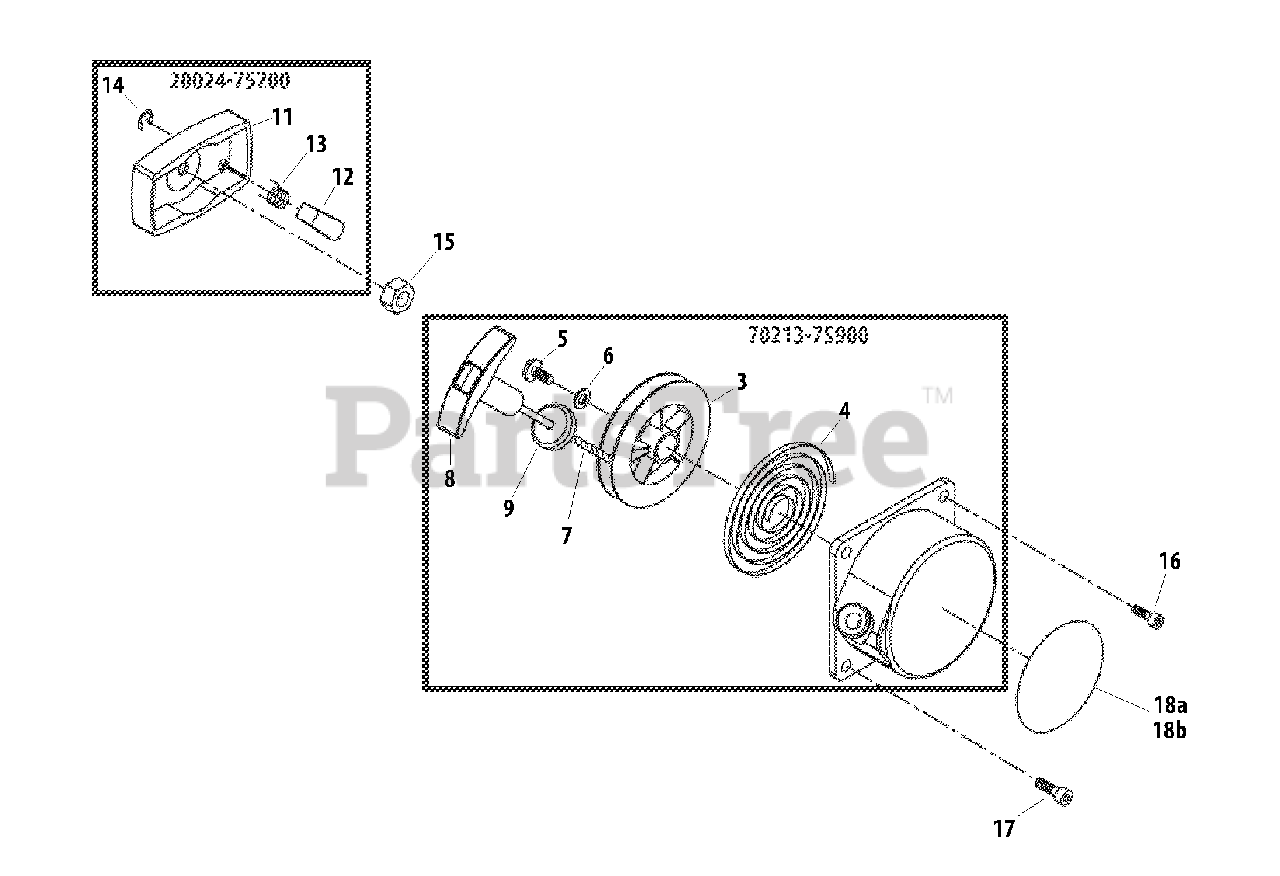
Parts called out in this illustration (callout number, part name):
3	REEL, ROPE
4	SPRING
5	SCREW
6	WASHER
7	ROPE
8	GRIP, STARTER
9	GUIDE, ROPE
11	CASE, PAWL
12	PAWL, STARTER
13	SPRING, RETURN
14	RING, RETAINING
15	NUT
16	SCREW - 5X20
17	SCREW - 5X25
18A	LABEL - MODEL
18B	LABEL - MODEL
20024-75200	STARTER PAWL ASSY
70213-75900	STARTER ASSY
